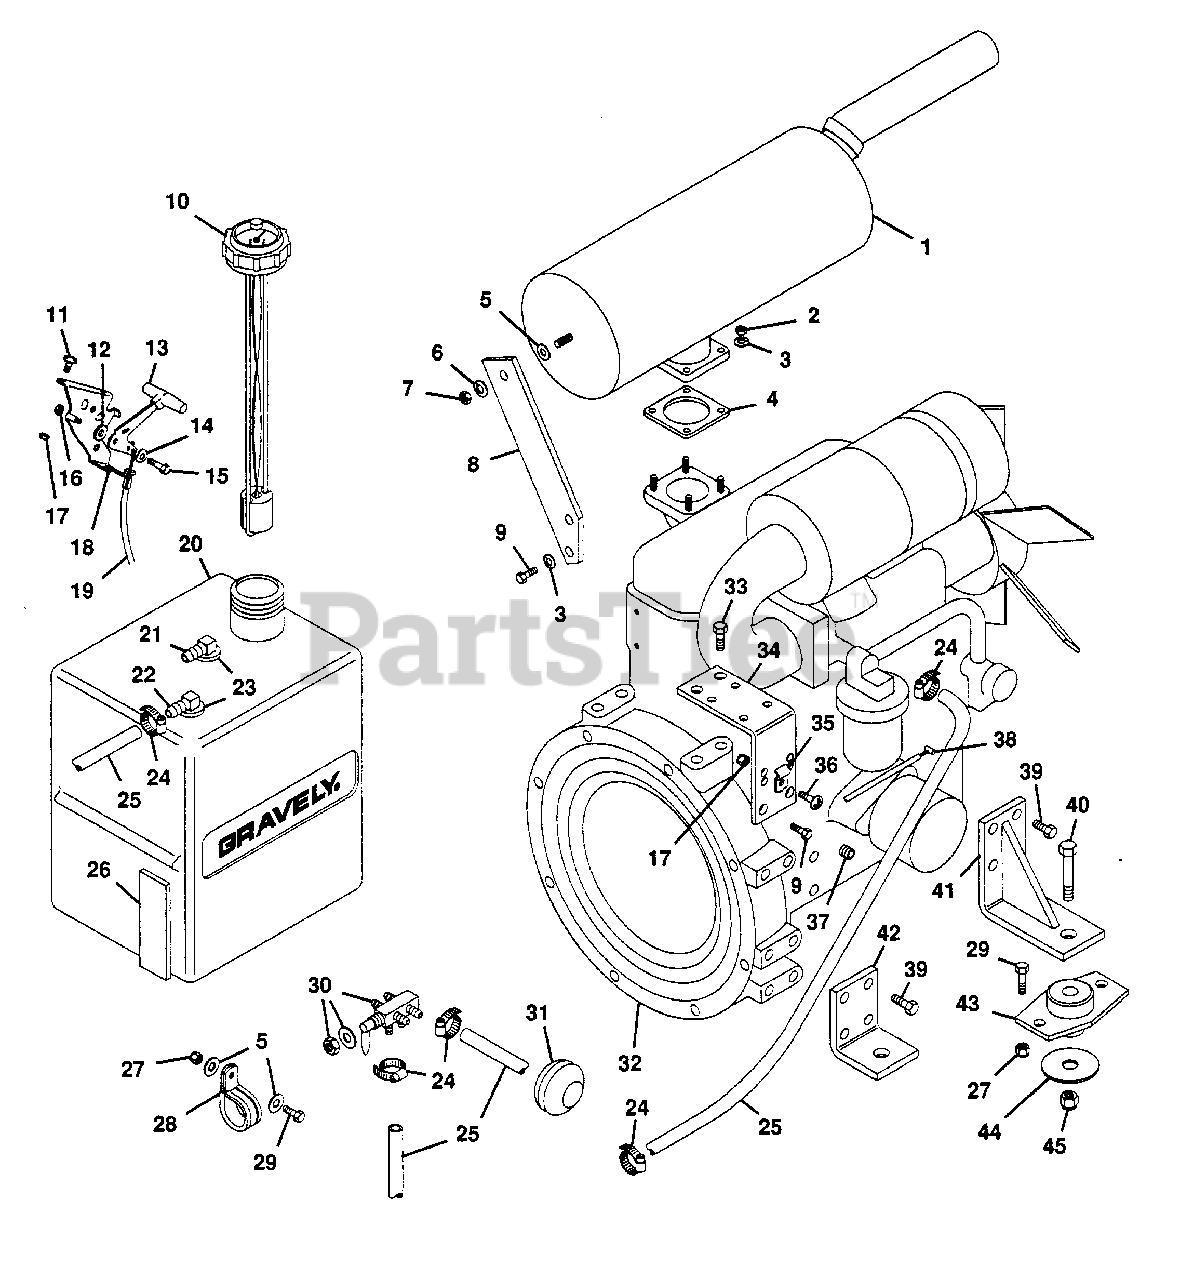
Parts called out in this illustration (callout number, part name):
1	Muffler, Yanmar
2	Nut, Hex M8 x 1.25
3	Washer, Lock 5/16 Reg.
4	Gasket, Exhaust
5	Washer, Flat .406x.812x.065
6	Washer, Lock 3/8 Reg.
7	Nut, Hex 3/8-16
8	Brace, Muffler
9	Bolt, Hex M8 x 1.25 16mm
10	Gauge, Fuel
11	Screw, Machine 10-24x.50 PHD
12	Washer, Friction
13	Assembly, Knob and Lever
14	Washer, Spring
15	Bolt, Hex 1/4-28x.75
16	Nut, Lock 1/4-28
17	Nut, Lock 10-24
18	Bracket, Mounting L.H.
19	Assembly, Conduit
20	Tank, Fuel
21	Fitting, Tank
22	Fitting, Tank
23	Bush., Flg. .375x1.06x.625 Rb.
24	Clamp, Hose
25	Line, Fuel .5 OD x .25 ID
26	Pad, Gas Tank
27	Nut, Lock 3/8-16
28	Clamp, Steel 1.00
29	Bolt, Hex 3/8-16x1.00
30	Valve, Fuel Control
31	Grommet
32	Engine, Yanmar
33	Bolt, Hex M10 x 1.5 16mm
34	Bracket, Control
35	Clip
36	Screw, Machine 10-24x.625 PHD
37	Plug, PT 1/4
38	Clamp, Swivel Wire
39	Bolt, Hex M10 x 1.5 20mm
40	Bolt, Hex 1/2-13x2.75
41	Weldment, Engine Mount
42	Mount, Engine
43	Mount, Engine
44	Washer, Snubbing
45	Nut, Lock 1/2-13
